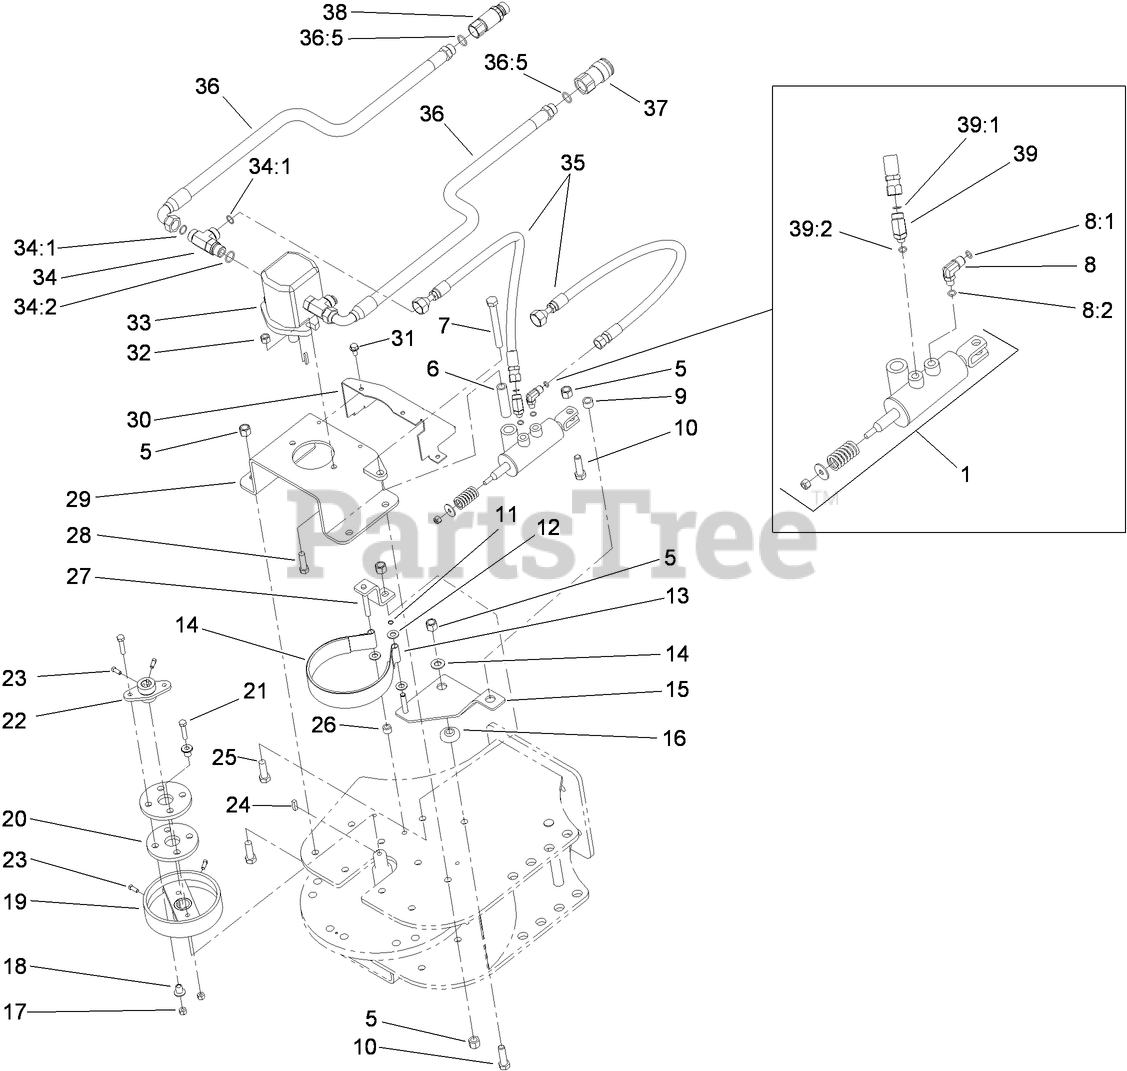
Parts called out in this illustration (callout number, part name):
1	CYLINDER ASM
5	NUT-LOCK, NI
6	SPACER-CYLINDER
7	SCREW-HH
8	FITTING-ELBOW 90
8:1	O-RING
8:2	O-RING
9	SPACER-CLEVIS
10	SCREW-HH
11	RING-RETAINING
12	WASHER-FLAT
13	BRAKE BAND ASM
14	WASHER-FLAT
15	BRAKE BRACKET ASM
16	SPACER-BRAKE
17	NUT-LOCK, NI
18	SPACER
19	Drum-Brake
20	COUPLING-RUBBER
21	SCREW-HH
22	HUB/SPACER ASM
23	SCREW-SET
24	KEY-SQUARE
25	SCREW-HH
26	SPACER-WHEEL
27	BRAKE ROD ASM
28	SCREW-HH
29	MOTOR MOUNT ASM
30	COVER-BRAKE
31	SCREW-HWHTF
32	NUT-LOCK, NI
33	MOTOR-HYD
34	FITTING-TEE
34:1	O-RING
34:2	O-RING
35	HYDRAULIC HOSE ASM
36	HOSE-HYDRAULIC
36:5	O-RING
37	COUPLER-FACE, FLUSH
38	NIPPLE-CONNECT, PRESSURE
39	ELBOW-45 DEG
39:1	O-RING
39:2	O-RING
